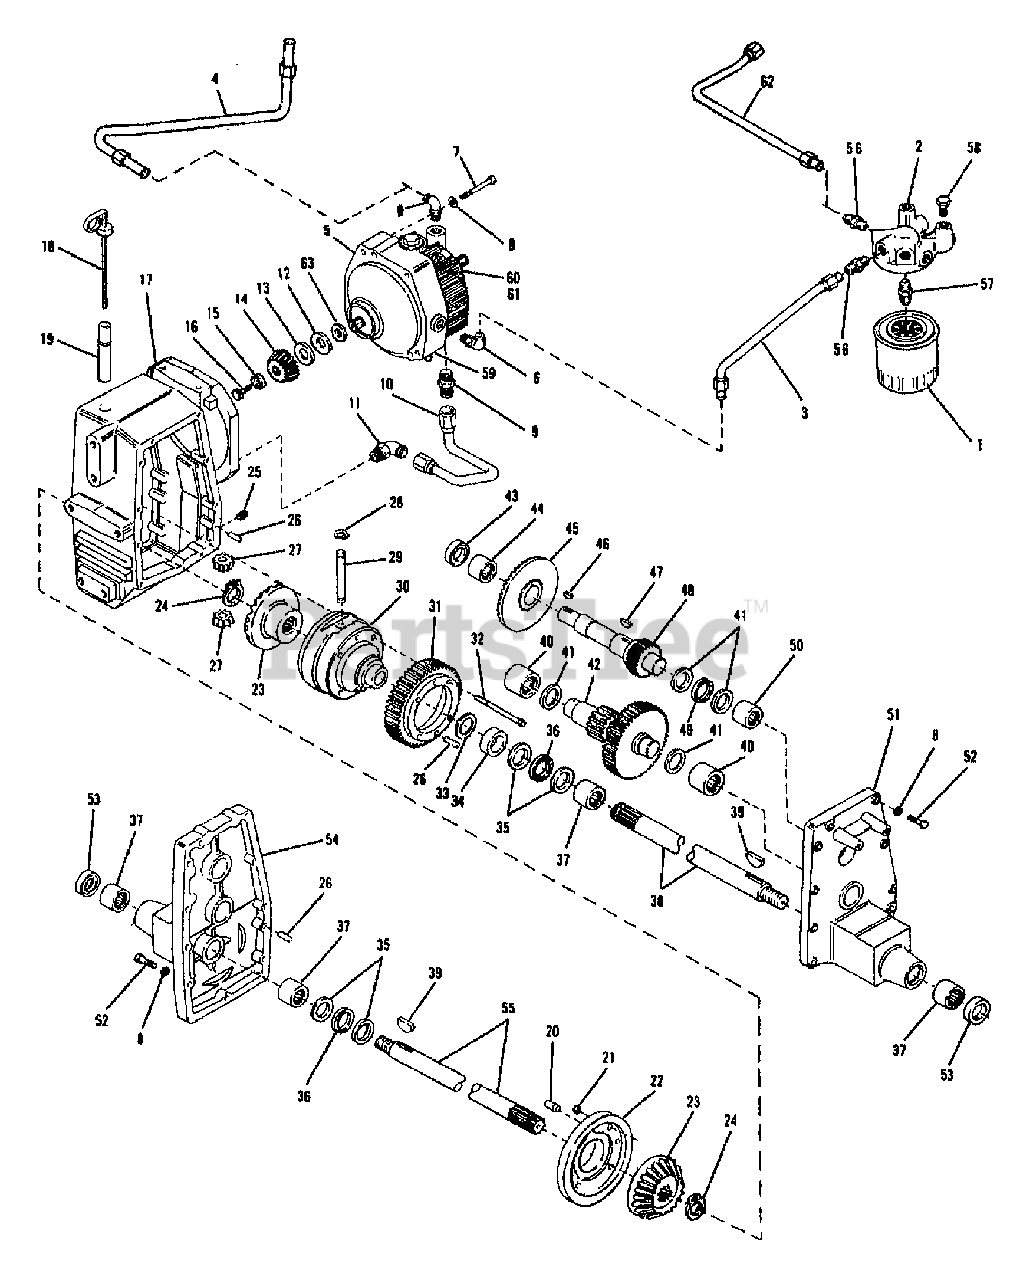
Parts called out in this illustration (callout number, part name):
1	FILTER-OIL
2	FILTER-MANIFOLD
3	ASSM-TUBE RETURN
4	ASSM-TUBE PUMP TO VALVE
5	TRANSMISSION-HYDRO
6	ELBOW
7	SCR-HH 3/8-16X2.75 G5 ZP
8	WASHER-LK .375 @ DEPL
9	CONNECTOR
11	ELBOW
12	WASHER-SHIM
13	WASHER-SHIM
14	PINION-BEVEL
15	SPACER-1.0X.25X.25
16	SCR-HH 1/4-20X.625 G5 ZP
17	HOUSING-TRANSAXLE
18	DIPSTICK
20	PIN-.312X.75
21	NUT-HEX/LK 5/16-18 G5ZP
22	COVER-DIFFERENTIAL
23	GEAR-23T
24	RING-HEAVY EXT HD 1.0 ID
25	PLUG-PIPE
26	PIN-DOWEL .375X1.00 ZP
27	PINION-10T
28	RING-HEAVY EXT .625 ID
29	PINION-SHAFT
30	CARRIER-DIFFERENTIAL
31	GEAR-AXLE 47T
32	SCR-HFLK 5/16-18X4.00 ZP
33	SHIM-1.875X1.013X.015
34	SPACER-1.5X1.01X.45
35	RACE-THRUST
36	BEARING-THRUST
37	BEARING-NEEDLE
38	AXLE-RH
39	KEY-WOODRUFF .312X1.12
40	BEARING-NEEDLE
41	RACE-THRUST
42	ASSM-GEAR CLUSTER
43	SEAL-OIL
44	BEARING-NEEDLE
46	KEY-WOODRUFF .25X.875
47	KEY-WOODRUFF .25X1
48	SHAFT ASSY., PINION
49	BEARING-THRUST
50	BEARING-NEEDLE
51	COVER-TRANSAXLE RH
52	SCR-HH 3/8-16X1.5 G5 ZP
53	SEAL-OIL
54	COVER-TRANSAXLE LH
55	AXLE-LH
56	CONNECTOR
57	COUPLING
59	SEAL-CONTROL SHAFT
60	SEAL-OIL
61	SHIELD-GRASS
62	ASSM-TUBE FILTER TO VALVE
63	WASHER-1.0X.64X.029
